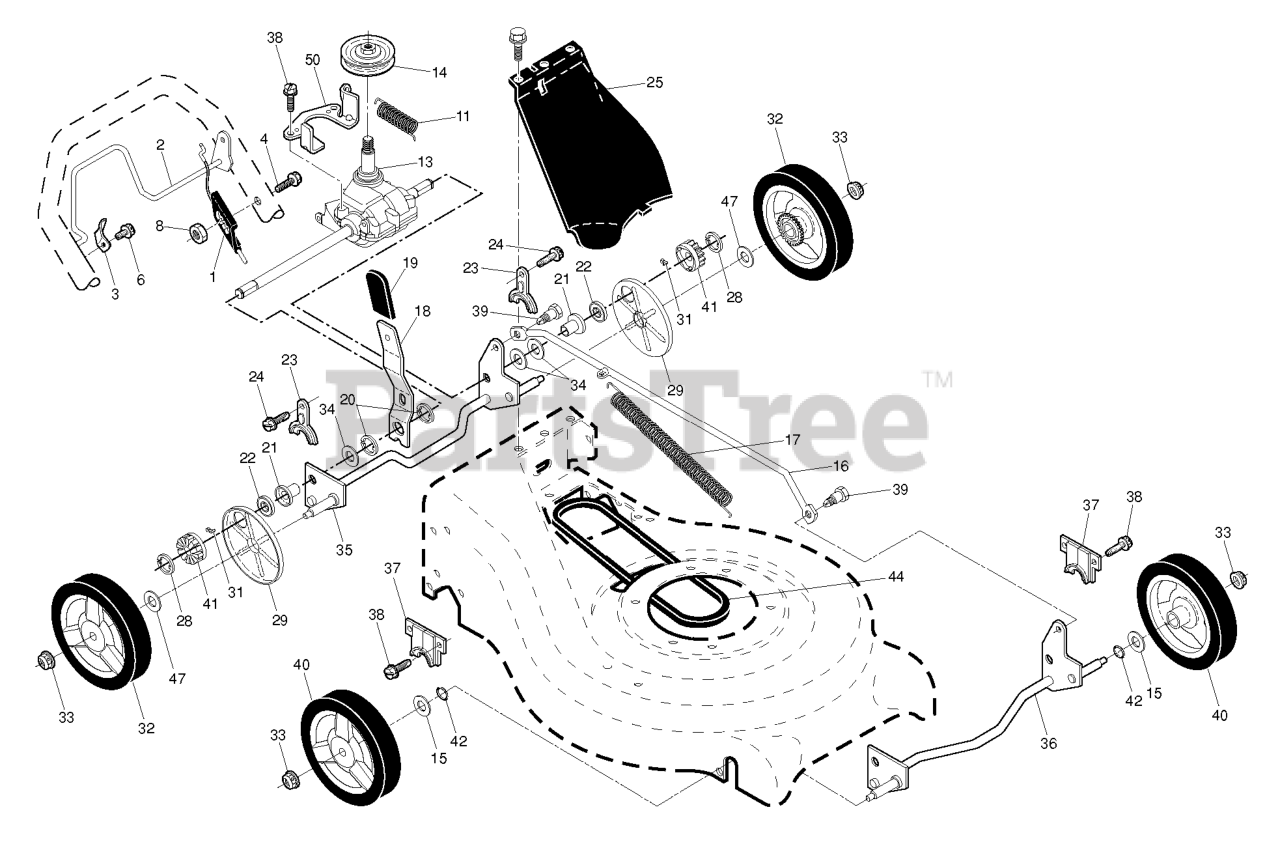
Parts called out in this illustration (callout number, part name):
3	DOWNSTOP BRACKET
8	NUT.HEX.FLANGE.1/4
13	TRANSMISSION.21.RWGD
14	PULLEY.RGD.SS.3.25OP
15	WASHER.FLAT.1/2
16	ROD.CONNECTING.SPT.BLACK
17	SPRING EXTENSION
18	SPRING.SELECTOR.
19	KNOB.EXT.ERGO.BLACK
21	BEARING SUPPORT
22	BEARING
23	BRACKET
24	SCREW 14-20 X 5/8
25	COVER.DR.ASM.199775X418.CE
28	E-RING 7/16 RE
29	COVER.DUST.WHEEL
31	PAWL, DRIVE
32	WHEEL.8X1.75.3SPK.RAD3.GREY
33	NUT.HEX.FLANGE.3/8-16.LO(3 2)
35	SHAFT ASSY REAR
36	SHAFT ASSY, FRONT
37	RETAINER.FRONT.SHAFT
39	SHOULDER BOLT SEMI GIMLET PT.
40	WHEEL & TIRES ASSY, FRONT
41	PINIION.14.TOOTH.RGD
42	O-RING..070X.487.NEOPRENE
44	RP.BELT.DRIVE.RGD.SS.WALK
47	WASHER FLUT
50	BRACKET.BELT.KEEPE/AUT*SUBS/2*
